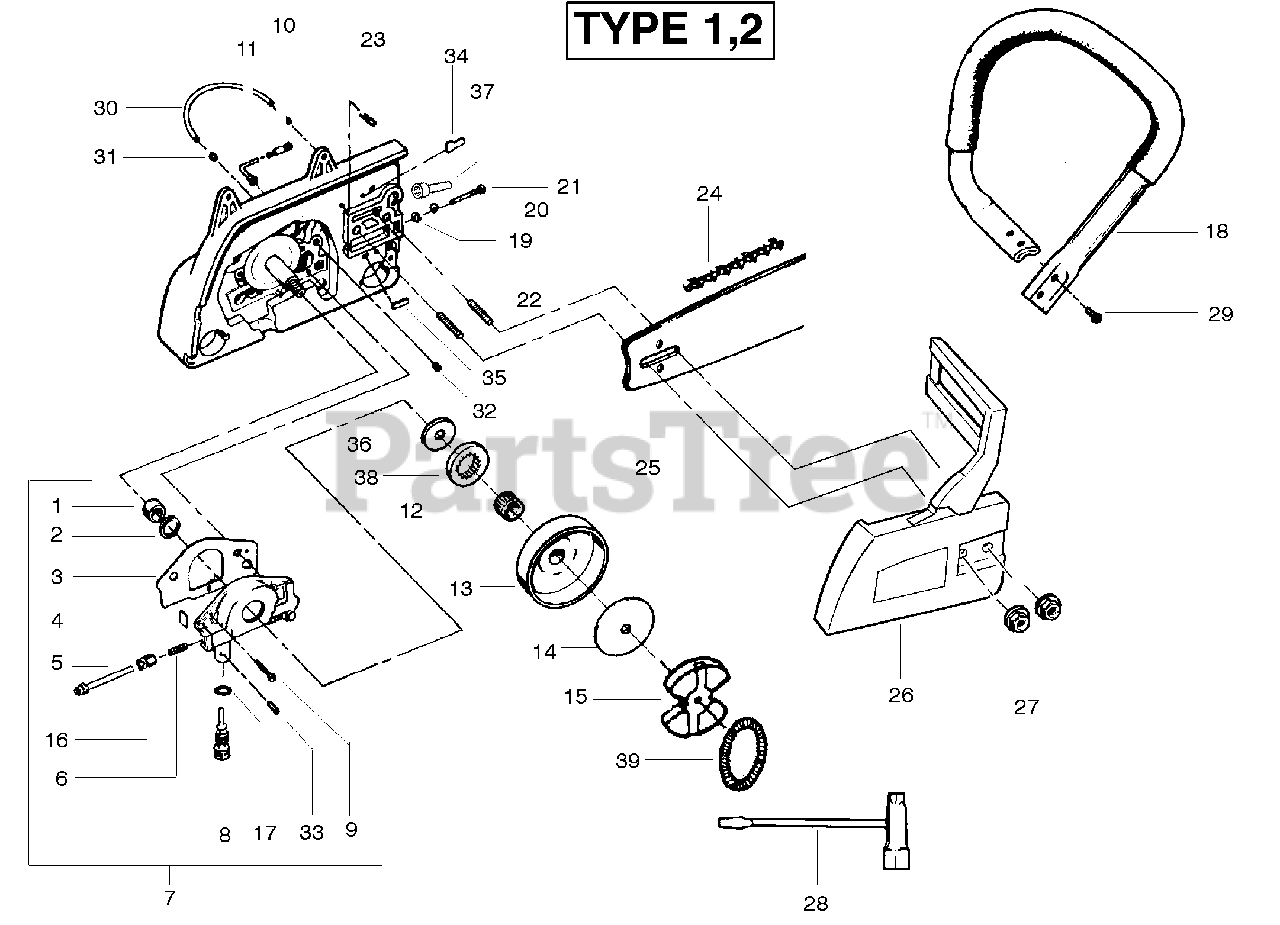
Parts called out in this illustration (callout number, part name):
1	Wire Worm Gear
2	Seal-Oil Pump
3	Gasket - Oil Pump
5	Shaft Ass’y.
6	Spring-Plunger
7	Oil Pump Ass’y.
8	Screw Oiler Adjusting
9	Screw
10	Oil & Filter Pickup
11	Oiler Intake Line
13	Drum & Adaptor Ass’y.
15	Clutch Ass’y.
18	Handlebar Ass’y.
19	Guide Bar Pin
20	Retainer-Bar Adjust
25	Bar 22"
26	Chain Brake Kit
27	Nut-Bar Mounting
28	Scrench Silver finish (1/2" x 3/4")
28	Scrench Gold finish (9/16" x 3/4")
32	Nut-Slotted Tube
33	Pin-Adjustment Screw
34	Chain Pad - Top
36	Thrust Washer
37	Crankcase Plug
38	Rim Floating (3/8)
39	Spring - Clutch
